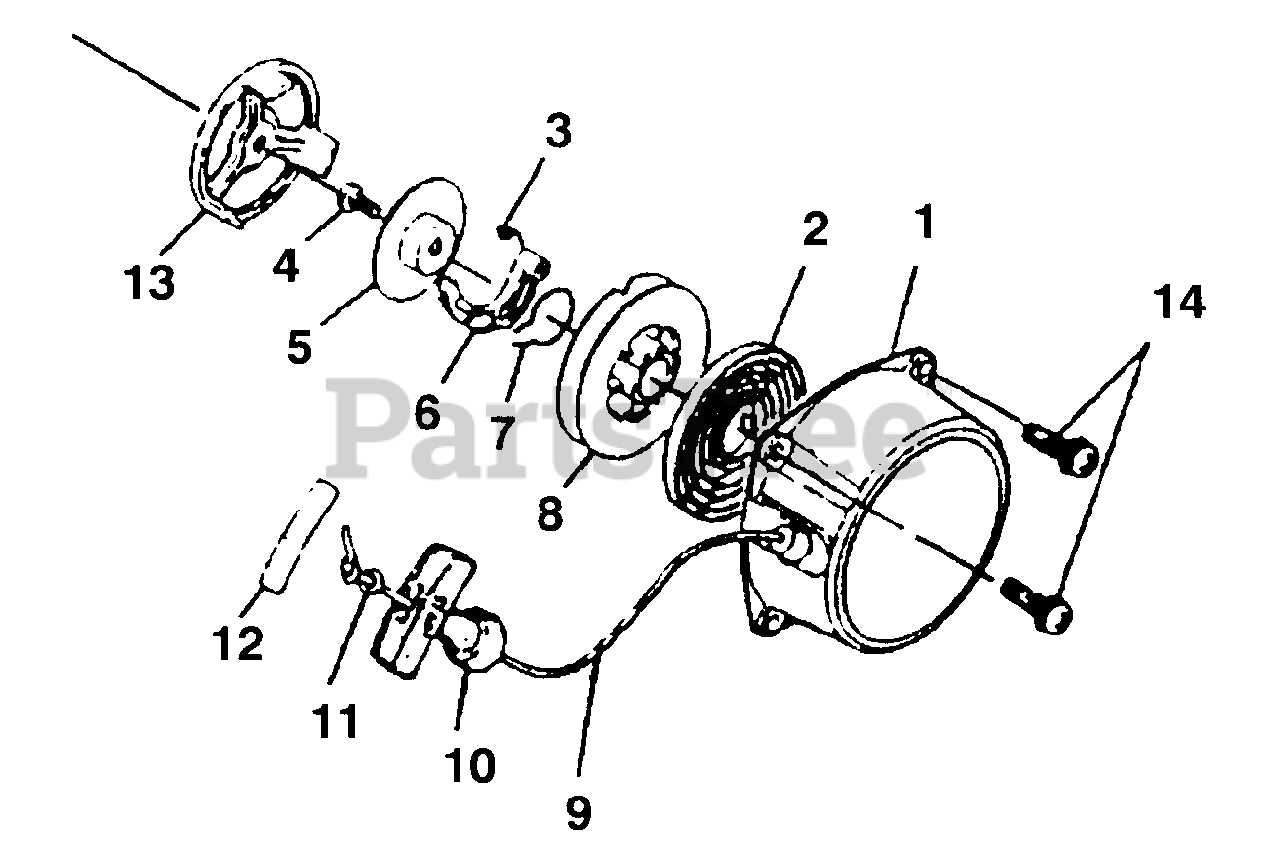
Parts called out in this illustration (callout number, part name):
1	STARTER CASE
2	SPRING, SPIRAL
3	RETURN SPRING
4	SCREW
7	FRICTION SPRING
14	SCREW
